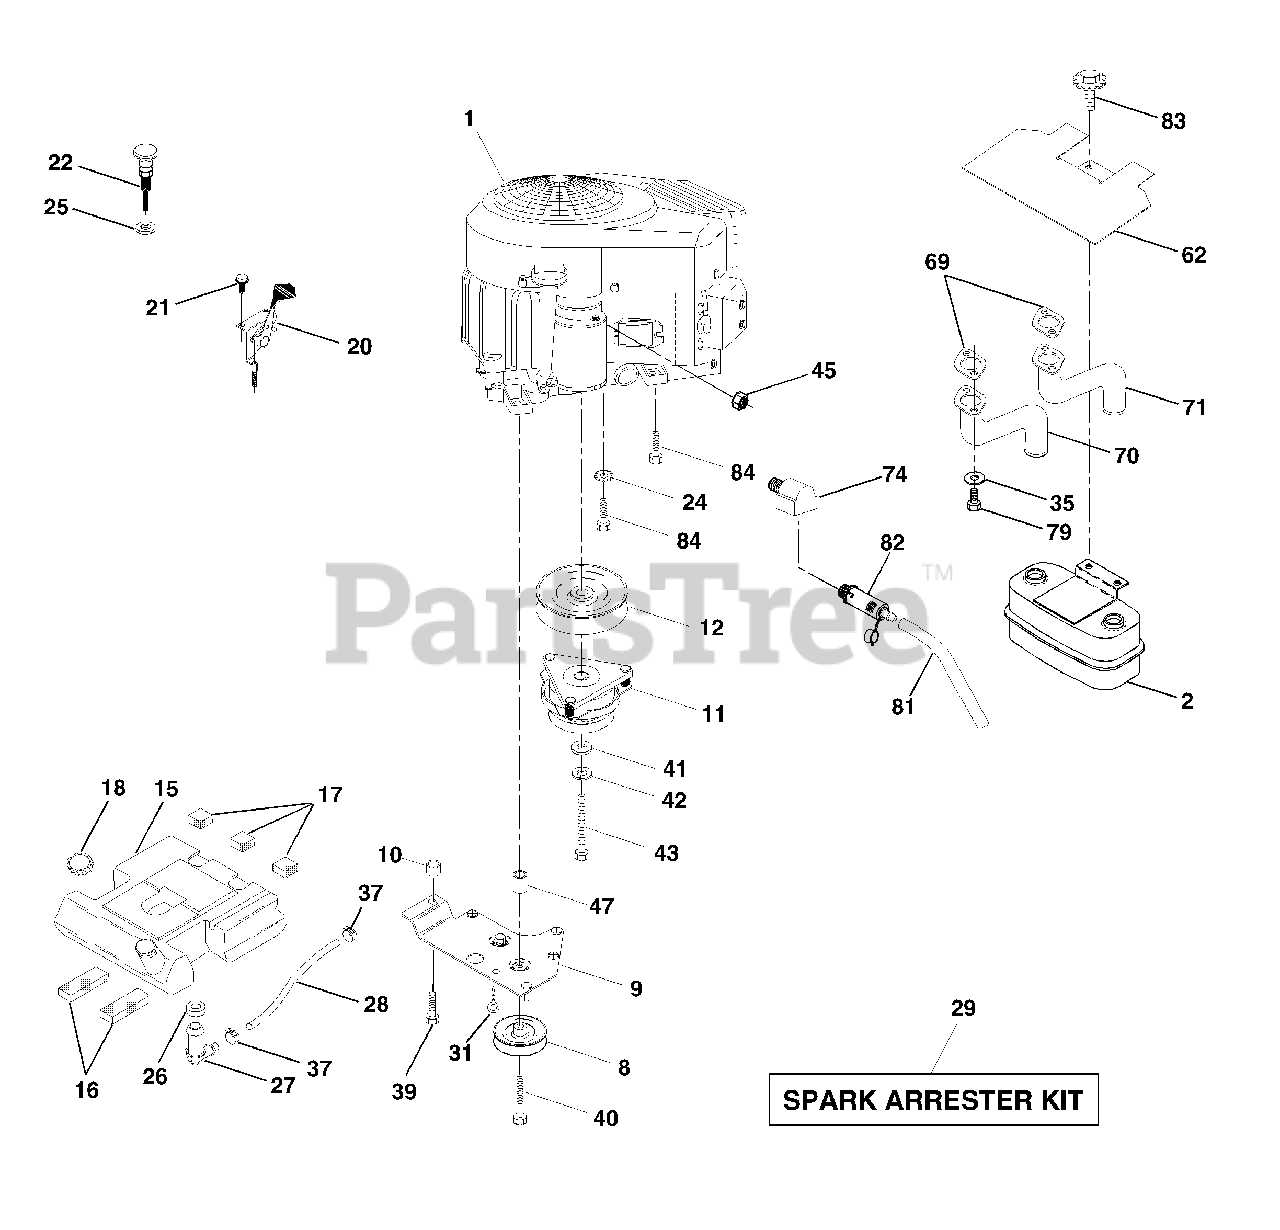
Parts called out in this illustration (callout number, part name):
2	Muffler Side
8	Pulley V-Idler
9	Keeper Asm. Belt Engine VGT
10	Bushing
11	Clutch Electric
12	Pulley Engine VGT Elect Clutch
15	Tank Fuel Rear 5.0
16	Pad Spacer
17	Pad Spacer
18	Cap Asm. Fuel
20	Control Throttle
21	Screw Hex Thd Cut 1/4 - 20 X 5/8
22	Control Choke
24	Washer Ext Tooth 3/8
25	Nut Keps 3/8-24 Unf
26	Bushing
27	Stem Tank Fuel
29	Spark Arrester Kit
31	Clip
35	Washer
37	Clamp Hose
39	Screw TT 3/8-16 x 2-1/4 UNC
40	Screw TT 3/8-16 x 4 UNC
41	Washer 1-1/2 OD X 15/32 ID X .250
42	Washer Lock 7/16
43	Bolt Hex 7/16-20 x 3.75 Gr. 5
45	Nut Keps Hex 1/4-20
47	Spacer
62	Shield Heat Muffler CV-Intek
69	Gasket
70	Tube Exhaust LH
71	Tube Exhaust RH
74	Elbow Street Brass
79	Screw Hex Hd Cap 5/16-18 x 3/4
81	Tube Drain Oil Easy
82	Plug Oil Drain Easy
83	Bolt 5/16-18unc X 1-3/4 W/Sems
84	Screw Thdrol 3/8-16 x 1-1/2
